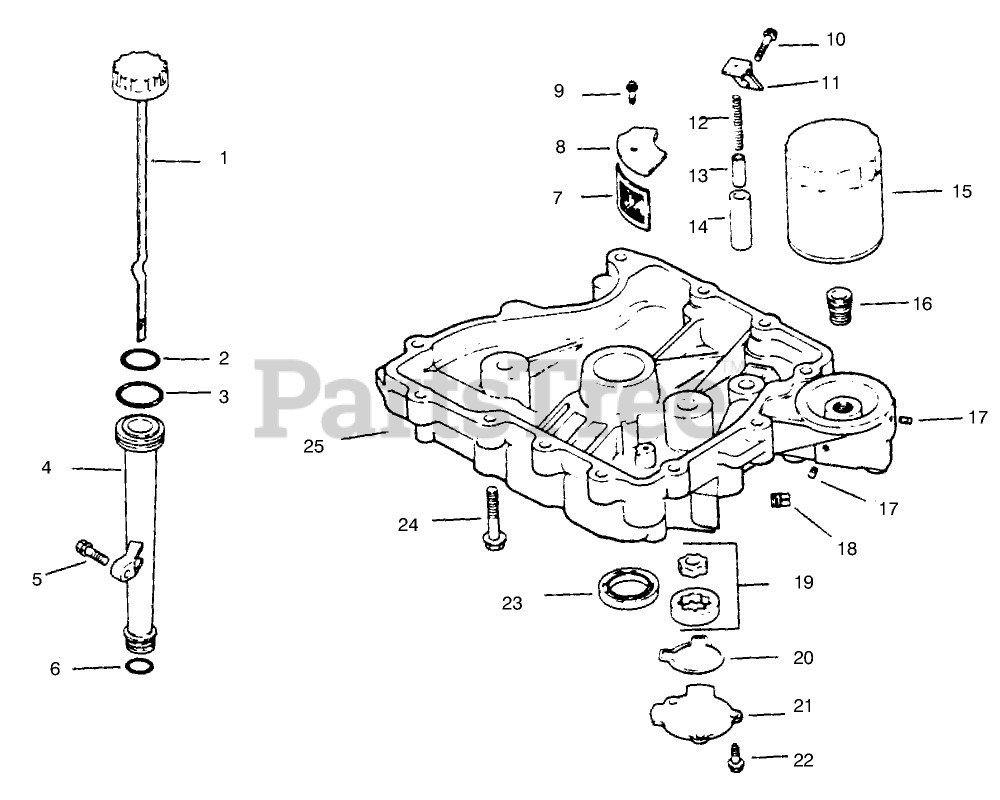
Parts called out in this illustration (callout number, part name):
1	Dipstick INC 2-3
2	"O"Ring
3	"O"Ring
4	Tube-Oil Fill
5	Screw
6	"O"Ring
7	Screen-Oil
8	Cover-Oil Screen
9	Screw
10	Screw
11	Bracket-Oil Pump Relief
12	Spring-Oil Relief Valve
13	Piston-Oil Relief Valve
14	Body-Oil Relief Valve
15	Filter-Oil
16	Adapter-Oil Filter
17	Plug-SH 1/8
18	Plug
19	Pump-Oil
20	"O"Ring-Pump Cover
21	Cover-Oil Pump
22	Screw
23	Seal-Crankshaft
24	Screw
25	Pan-Oil
